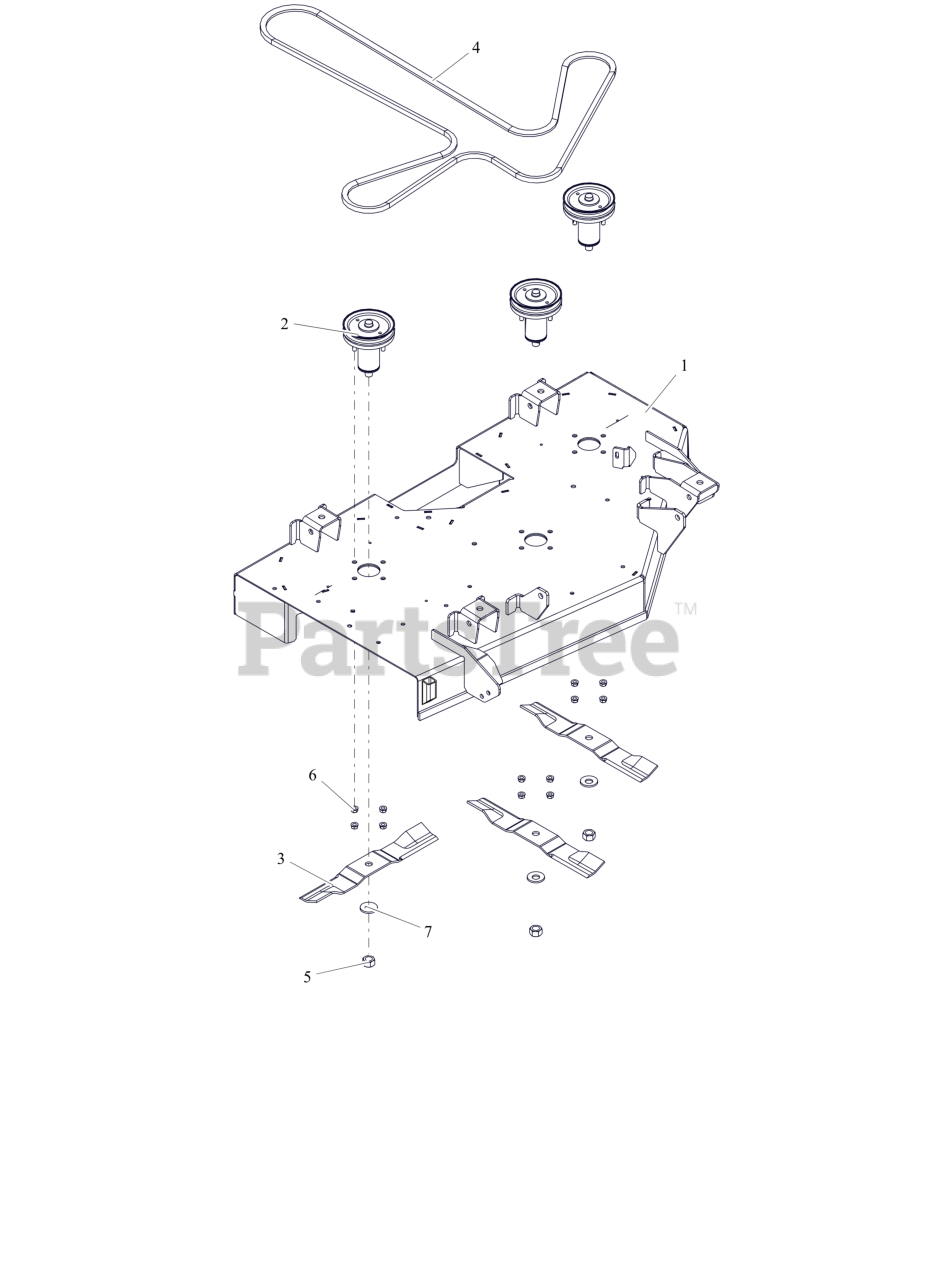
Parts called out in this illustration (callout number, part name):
1	WLDMT, DECK 42" (ORANGE)
2	KIT- DECK SPINDLE ASSM- 42"
3	BLADE, MOWER 15.00"
4	V-BELT, 4L-WRAPPED
5	NUT-STD .625-18 ZCC
6	NUT,LK-CTR-FLG .31-18 GF ZCC
7	WSHR-BLVL .669X1.535X.138
